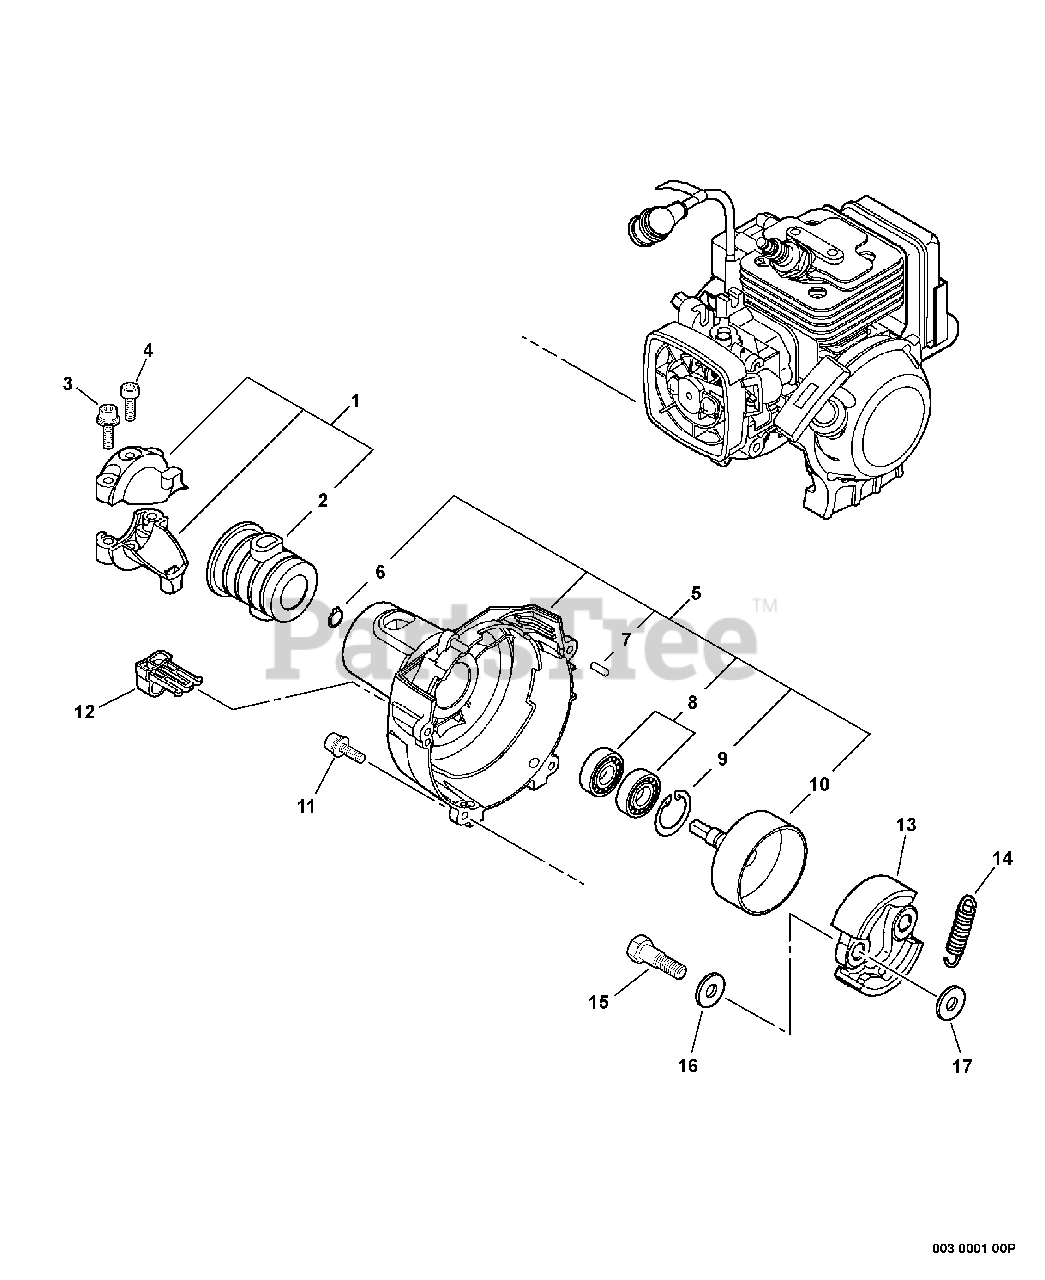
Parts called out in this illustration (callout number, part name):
1	MAIN PIPE CLAMP KIT
2	CUSHION
3	SCREW - 5X25
4	SCREW - 5X12
5	FAN CASE ASSY
6	RING, RETAINING - 12
7	PIN - LOCATING
8	BEARING, BALL - 6001
9	RING, RETAINING - 28
10	DRUM, CLUTCH
11	SCREW - 4X16
13	SHOE, CLUTCH
14	SPRING, CLUTCH
15	BOLT, CLUTCH
16	WASHER - SPRING
17	WASHER - 6
